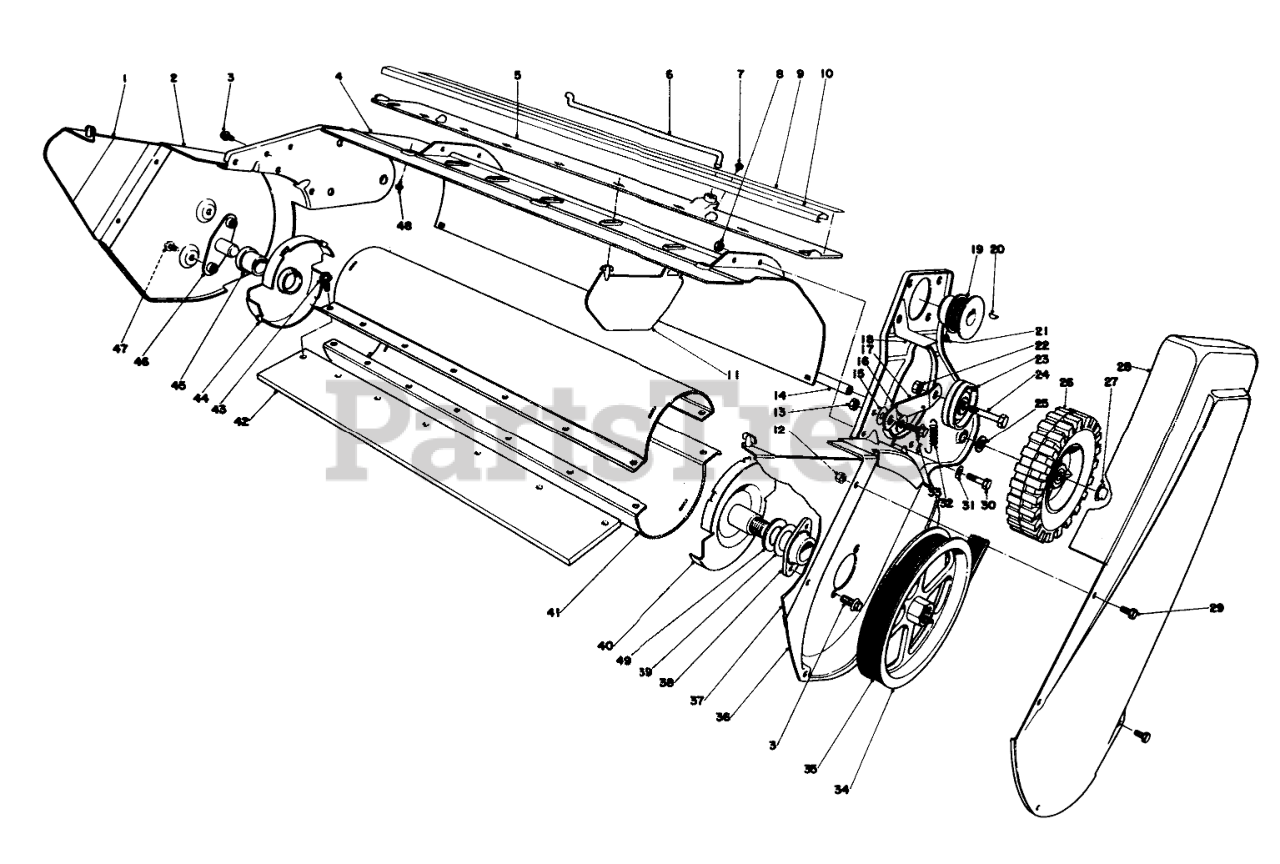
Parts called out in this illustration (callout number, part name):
1	Vane-Outside R.H.
2	Sideplate R.H.
3	SCREW
4	Housing
5	Vane Mount
6	Linkage-Vane Adj.
7	10-16 X 3/8 THDG SCREW
8	NUT-LOCK, CONE
9	Decal Warning
10	Moulding
11	Vane
12	NUT-LOCK, NI
13	NUT-LOCK, CONE
15	Washer
16	WASHER
17	Idler Arm
18	Leaf Spring-Idler
19	Pulley
20	KEY-WOODRUFF
21	SCREW-SET, HSH
22	NUT-LOCK, NI
23	IDLER PULLEY
24	SCREW-HH
25	WASHER-FLAT
26	WHEEL
27	RETAINER-PUSH ON
28	Drive Cover
29	SCREW-HWH
30	SCREW-HH
31	WASHER-FLAT
32	IDLER SPRING
33	SCREW-SHOULDER
34	Rotor Pulley
35	BELT - DRIVE
36	Side Plate L.H.
37	Vane-Outside L.H.
38	Rotor Bearing
39	WASHER-THRUST
40	Drive Shaft & End Cap
41	ROTOR SHELL
42	ROTOR BLADE
43	SCREW-TAP
44	End Cap (Incl. Ref. No.45)
45	ROTOR BUSHING
46	Rotor Shaft
47	1/4-20 X 3/8 SEMS SCR
48	Screw
49	WASHER
